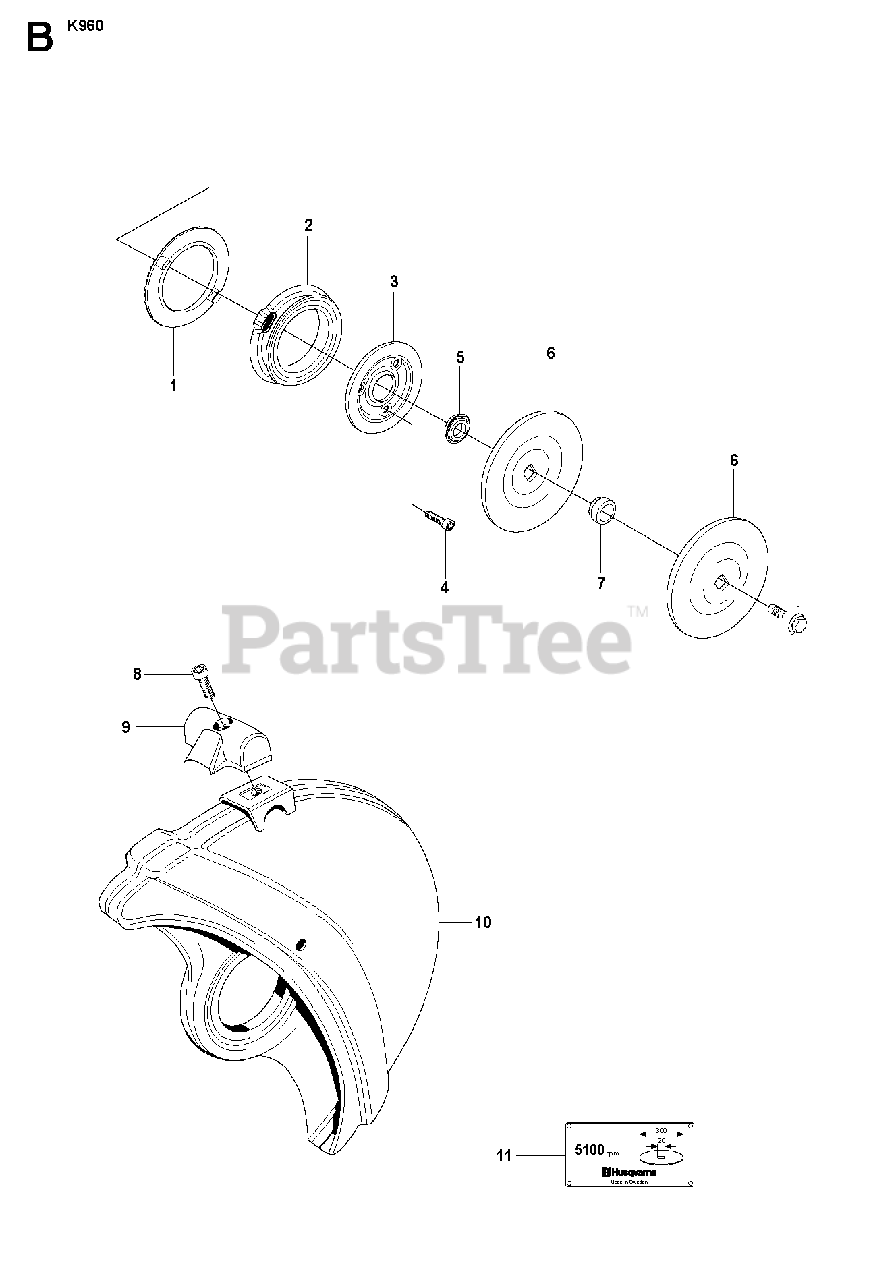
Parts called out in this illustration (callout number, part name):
5	SUPPORT FLANGE
6	FLANGE WASHERDiam 105
6	FLANGE WASHERDiam 116
7	KITDiam 22,2
7	BUSHINGDiam 30,5
8	SCREW IHSCM
10	WHEEL GUARD"12"". Incl. 2, 9, 10"
10	WHEEL GUARD"14"". Incl. 2, 9, 10"
10	GUARD"16"". Incl. 2, 9, 10"
11	LABEL"12"". Diam 1"""
11	LABEL"12"". Diam 20 mm"
11	LABEL"14"". Diam 1"""
11	LABEL"14"". Diam 20 mm"
11	LABEL"16"". Diam 1"""
11	LABEL"16"". Diam 20 mm"
